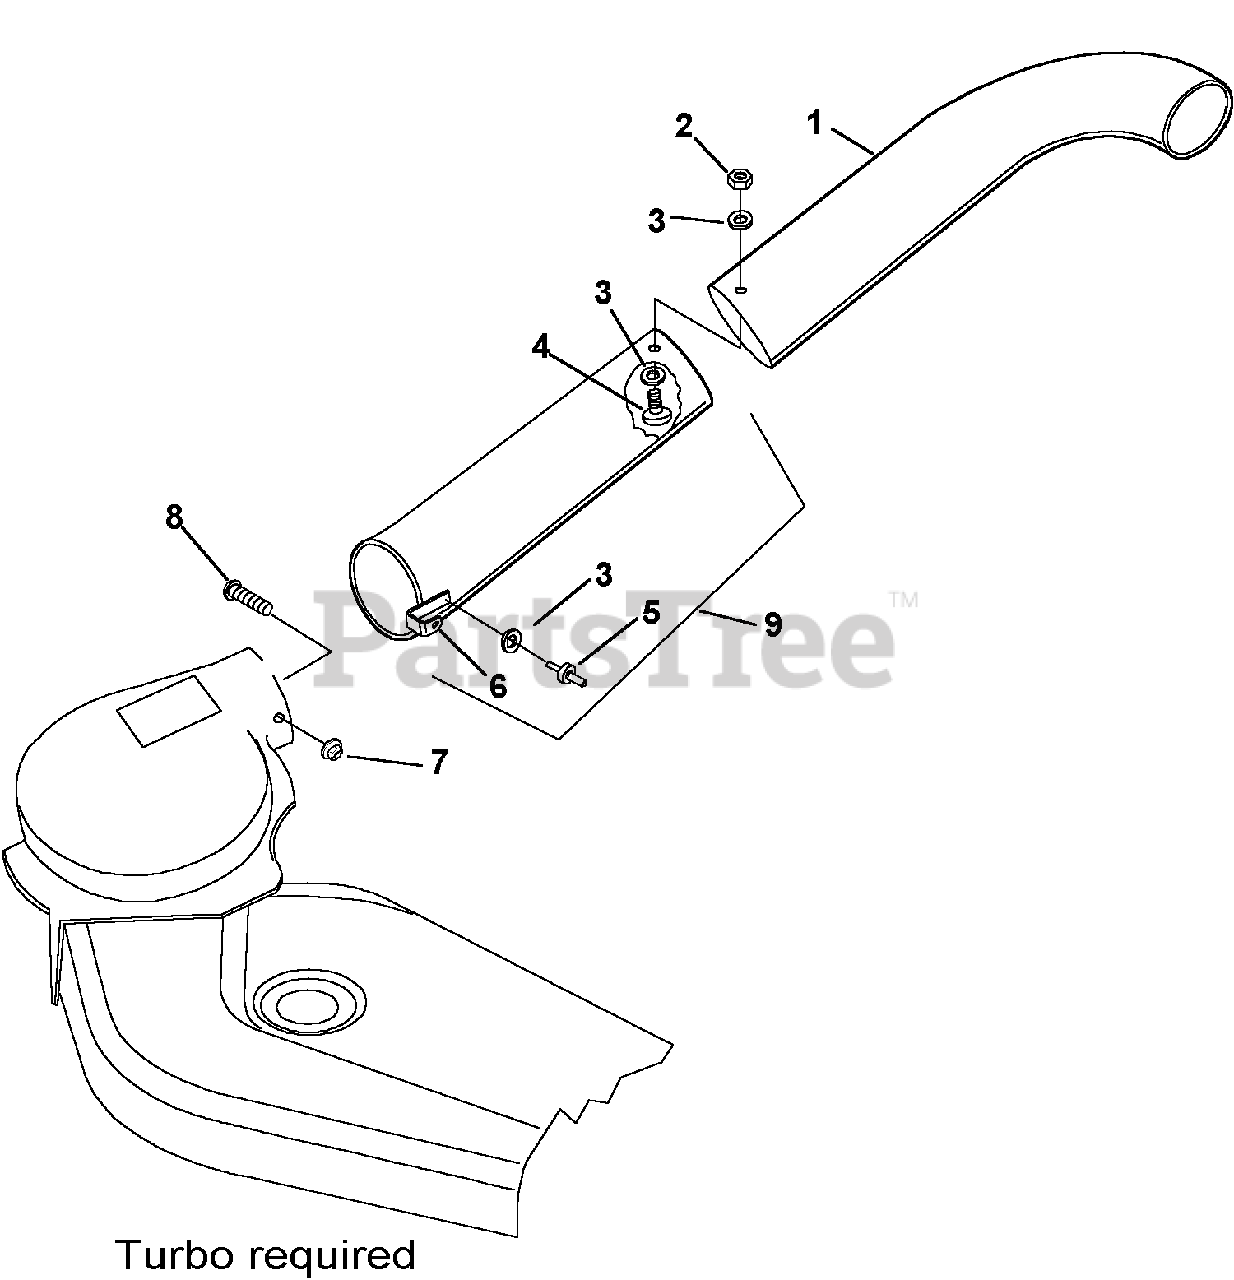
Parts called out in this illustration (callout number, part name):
1	ELBOW, Upper
2	NUT, Hex Washer Assembly, #10-32
4	SCREW, Truss Head, #10-32 x 1/2
6	CLIP, Spring
7	NUT, Hex Flange Lock, 1/4-20
8	CARRIAGE BOLT, 1/4-20 x 5/8
9	TUBE & SPRING ASSEMBLY (Incl. Ref. Nos. 3, 5, & 6)
